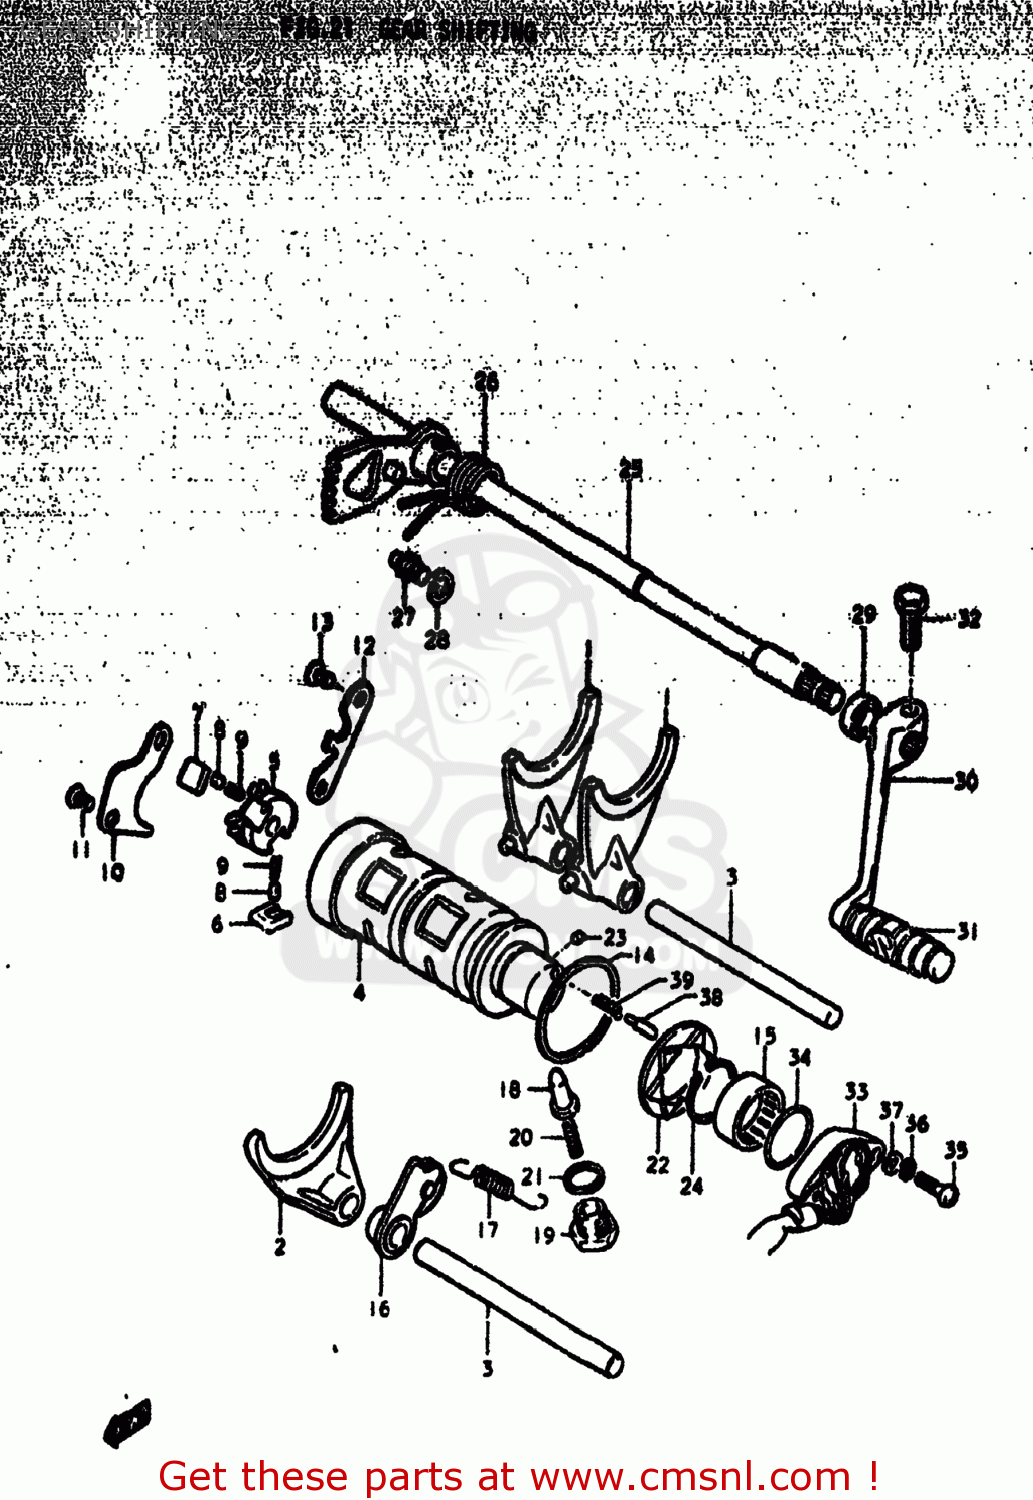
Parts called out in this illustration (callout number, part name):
1	FORK,GEAR SHIFT NO.1
2	FORK,GEAR SHIFT NO.3
3	SHAFT,GEAR SHIFT FORK
4	CAM,GEAR SHIFT
5	RETAINER,GEAR SHIFT CAM
6	PAWL,GEAR SHIFT NO.1
7	PAWL,GEAR SHIFT NO.2
8	PIN(5X8)
9	SPRING
10	LIFTER,GEAR SHIFT PAWL
11	SCREW 5X12
12	GUIDE,GEAR SHIFT CAM
13	SCREW
14	WASHER(40X45X1)
15	BEARING(25X32X12)
16	STOPPER,GEAR SHIFT CAM
17	SPRING
18	STOPPER,GEAR SHIFT CAM NO.2
19	HOLDER,GEAR SHIFT CAM STOP SPR
20	SPRING
21	GASKET(14X19.2X2) (NAS)
22	PLATE,GEAR SHIFT CAM STOPPER
23	PIN 4X6
24	CIRCLIP
25	SHAFT,GEAR SHIFT
26	SPRING
27	STOPPER,GEAR SHIFT CAM
28	LOCK WASHER
29	OIL SEAL
30	LEVER ASSEMBLY,GEAR SHIFTING
31	RUBBER,GEAR SHIFT PEDAL
32	BOLT
33	BASE ASSEMBLY,NEUTRAL SWITCH TERMINAL
34	O-RING (D:2.4 ID:26.2)
35	SCREW 5X20
36	LOCK WASHER
37	WASHER
38	PIN(5X15.5)
39	SPRING
